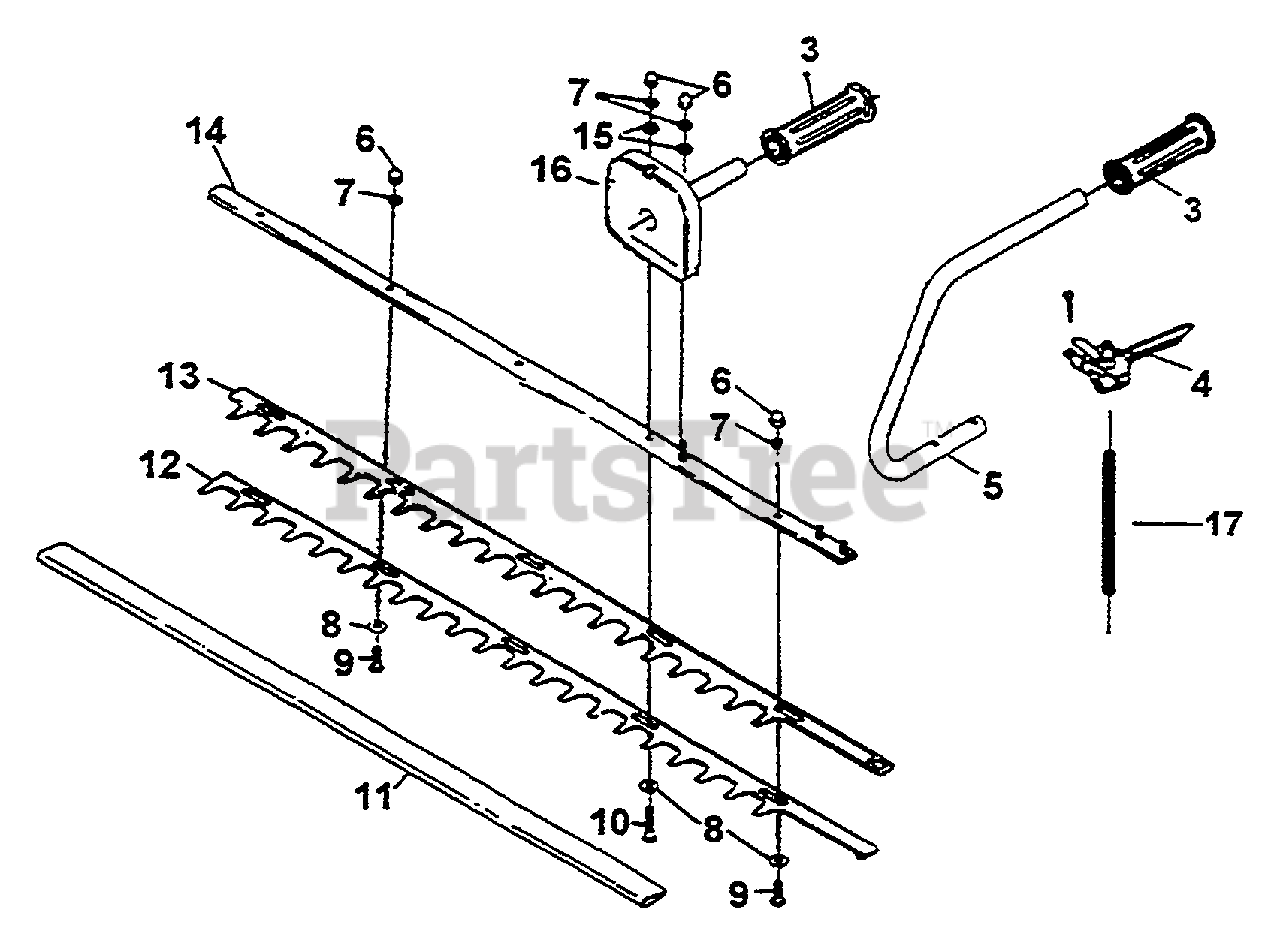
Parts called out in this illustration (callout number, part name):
3	GRIP
4	LEVER THROTTLE
5	HANDLE, REAR
11	COVER, BLADE
12	BLADE, LOWER
13	BLADE, UPPER
14	CUTTER GUIDE
16	HANDLE, FRONT
17	CABLE, THROTTLE
